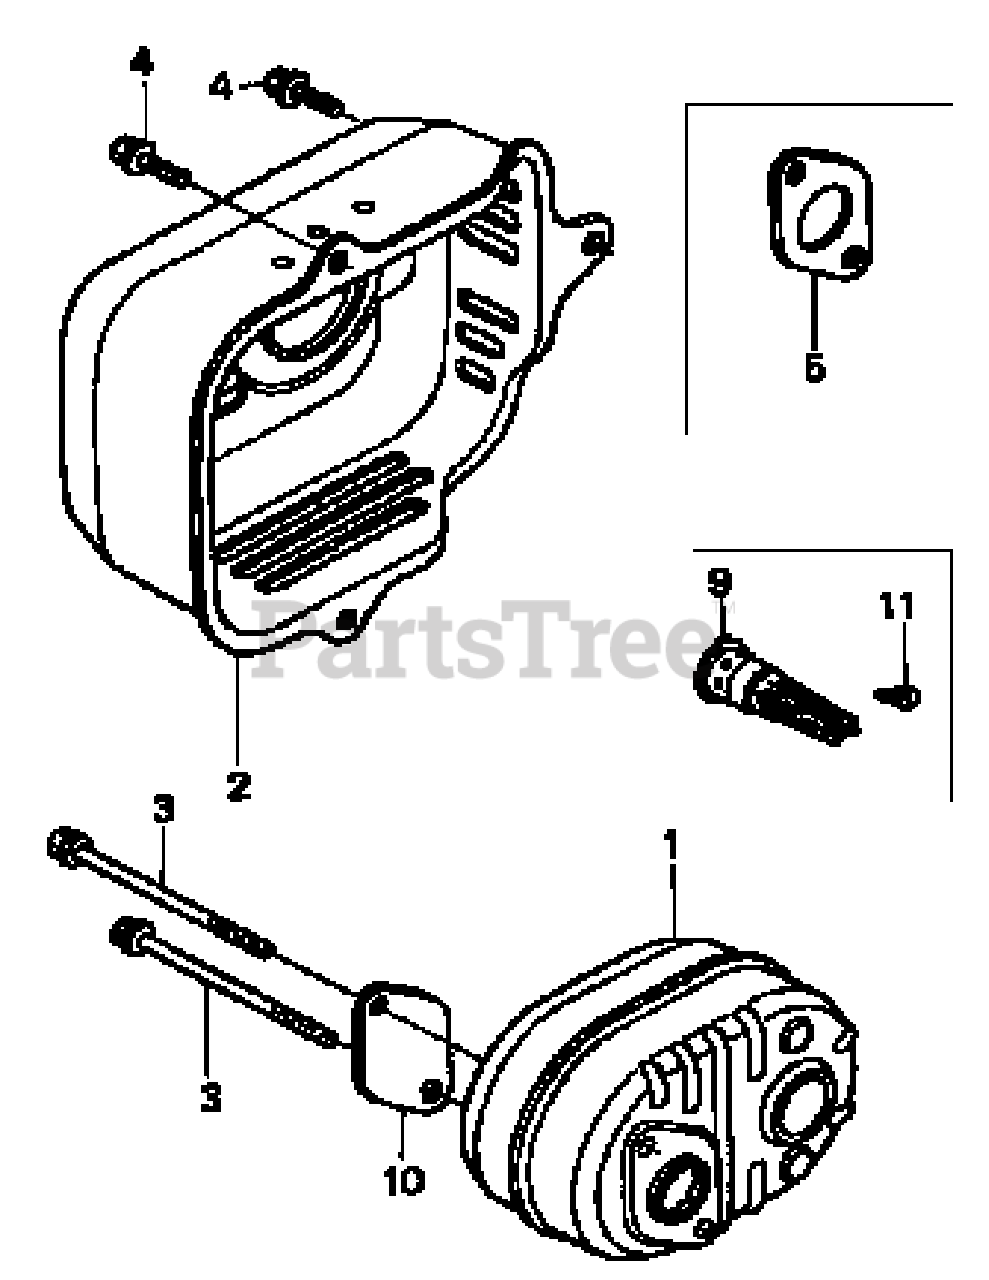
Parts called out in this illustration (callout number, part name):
1	Muffler
2	Muffler Protector
3	Flange Bolt (6x79)
4	Flange Bolt
5	Muffler Gasket
9	Spark Arrester
10	Arrester Number Plate
11	Tapping Screw (4x6)
